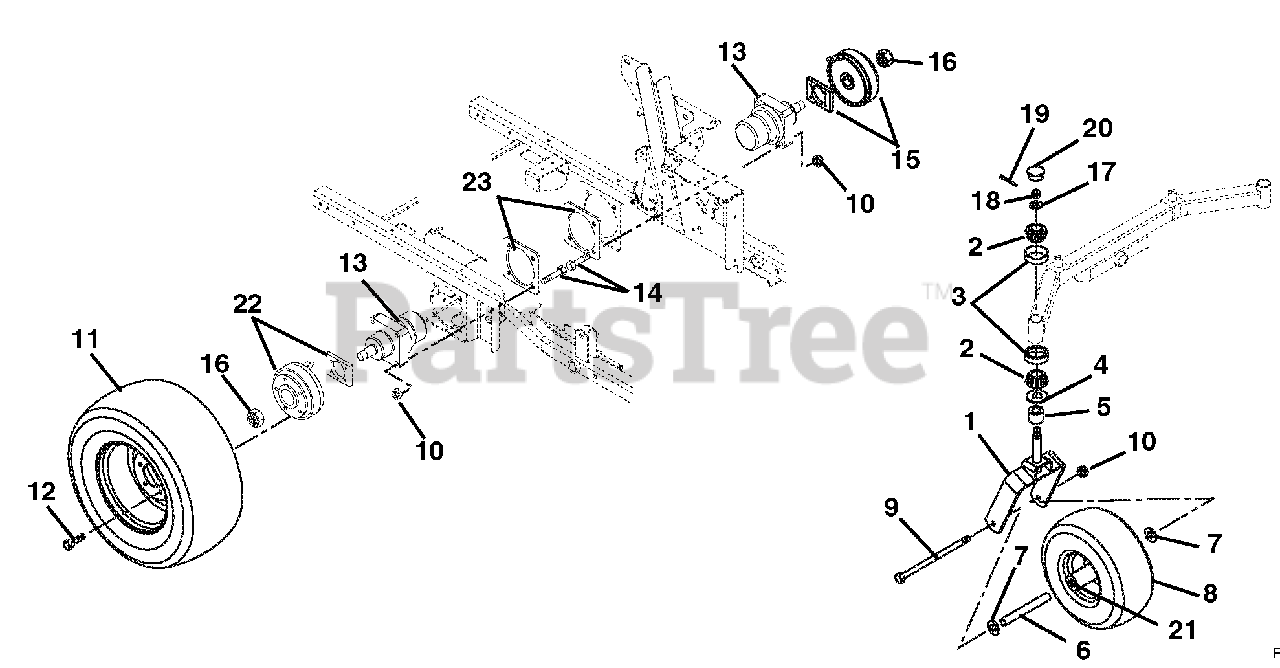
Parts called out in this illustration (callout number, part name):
1	Fork, Front
2	Bearing, Cone w/ Grease
3	Bearing, Cup 1.980 x .420
4	Bearing Seal 1.5 x 2 x .18
5	Spacer, PM, 1.03 I.D. x 1.5 O.D. x .375
6	Spacer, Wheel
7	Washer, Flat Steel .515 x 1.625 x .250
8	Wheel/Tire Assembly
9	Bolt, Hex .50-13 x 9.00 Grade 5
10	Nut-Locking-Top-Flange .50-13
11	Tire/Wheel Assembly 24 x 12-12
12	Bolt, Lug .50-20 x 1.38 Grade 8, 60 Degree
13	Hydraulic Wheel Motor (includes 16)
14	Bolt, Wheel Motor .50-13 x 2.75
15	Brake, Right Hand Park
16	Nut, Lock Jam Patch (Included with 13)
17	Washer, Flat Steel .755 x 1.375 x .062
18	Nut, Slotted .75-16
19	Pin, Cotter .16 x 1.00
20	Cap, Dust
21	Bearing, 25mm I.D. x 52mm OD x 15mm
22	Brake, Left Hand Park
23	Plate, Motor Support
